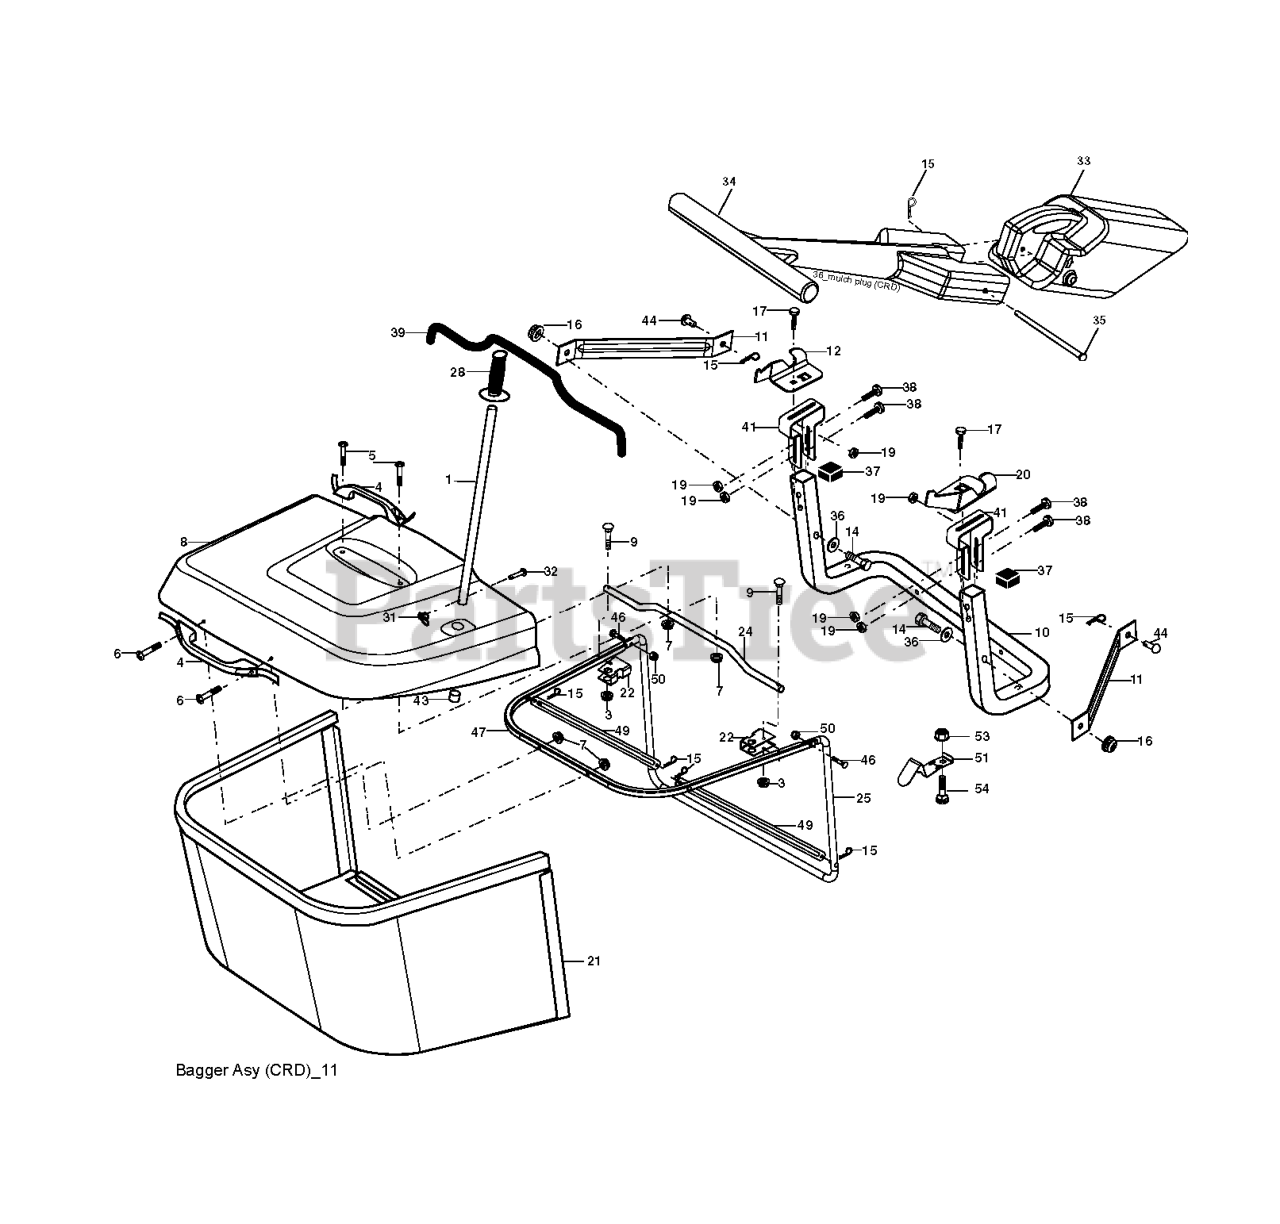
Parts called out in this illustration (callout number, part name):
1	TUBE HANDLE
3	NUT T
4	HANDLE.BAGGER.W/LVRS.BLK.CRD
5	SCREW.PAN.HEAD
6	REPL BY 532 75 00-29
8	COVER.PNT.BGR.CRD.WSLOTS.MS668
9	Bolt Carriage 1/4-20 x 2.25d x Gr.5
10	TUBE
11	BRACKET.SUPPORT.UPPER.BAG.CRD
12	BRKT PIVOT
14	BOLT-HEX EAK
15	RETAINER-SPRNG RB
16	NUT LOCK FLG 3/8-16 UNC
17	RP BOLT 5/16-18 X3/4 ZN/YEL GR
19	NUT LOCK HEX FLANGE 5/16-18
20	BRKT.PIVOT.RH.CRD
22	BRKT.SIDE.BAG.CRD
24	TUBE.PIVOT.BAG.CRD.BLACK
25	PIPE
28	GRIP.HANDLE.BLACK
31	RETAINER CLIP
32	RIVET,DRILLED
33	MULCH PLUG, CTH150
34	HANDLE.MULCHER.92.CRD (2 2)
36	WASHER
37	Plug Support Bagger CRD
38	BOLT.5/16-18X2.5
39	SEAL.TRIM.37'
41	BRKT.VERT.ADJ.BAGGER.CRD
43	PLUG, TUBING END
46	BOLT.CARRIAGE.5/16-18
47	PIPE
49	ROD
50	NUT.71038.31-18.HEX.NYLOCK
51	LATCH
53	NUT
54	BOLT
